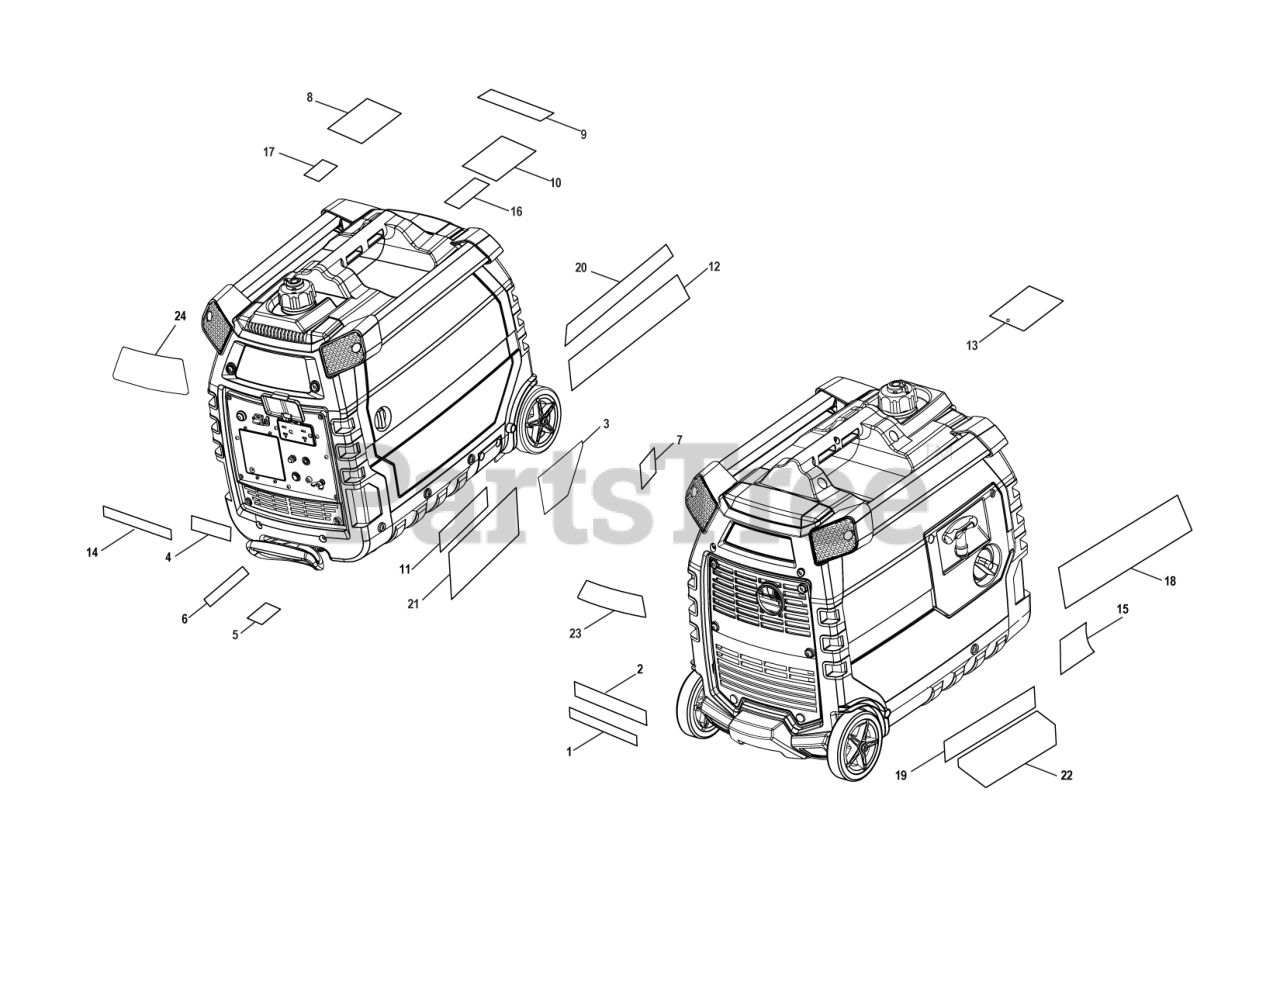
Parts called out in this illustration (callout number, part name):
1	LABEL (EN/FR), GROUND WARNING
2	LABEL, HOT SURFACE
3	LABEL, FIRE DISTANCE
4	LABEL, LED LIGHT LEGEND
5	LABEL, UPRIGHT STORAGE
6	LABEL, HANDLE RELEASE
7	LABEL, MAINTENANCE
8	LABEL, DANGER
9	LABEL, EXHAUST DIRECTION
10	LABEL, CPSC
11	LABEL, DO NOT TAMPER
12	LABEL, CO WARNINGS/SHUT OFF
13	LABEL, NOTICE
14	LABEL, FCC ID
15	LABEL, CHOKE
16	LABEL, FUEL STABILIZER (LEFT)
17	LABEL, FUEL STABILIZER RIGHT
18	LABEL, ECHO LOGO
19	LABEL, PERFORMANCE
20	LABEL, MAINTENANCE DOOR
21	LABEL, CONNECT LOGO
22	LABEL, CONTROL
23	LABEL, ECHO HOOD LOGO
24	LABEL, CONNECT LOGO - DOOR
